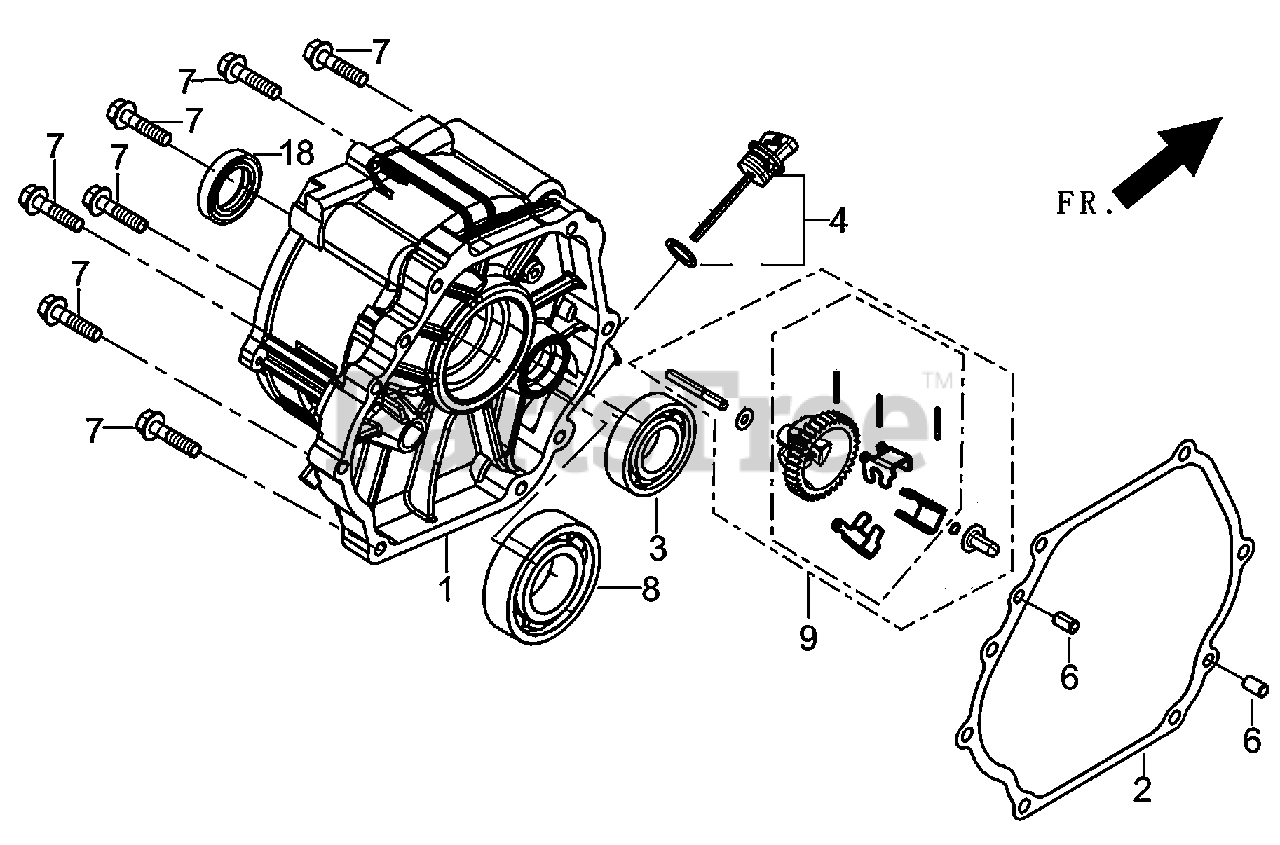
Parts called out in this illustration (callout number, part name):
1	COVER, CRANKCASE
2	GASKET, CRANKCASE
4	DIPSTICK SUBASSEMBLY, OIL
9	GEAR ASSY, GOVERNOR
18	SEAL, OIL
